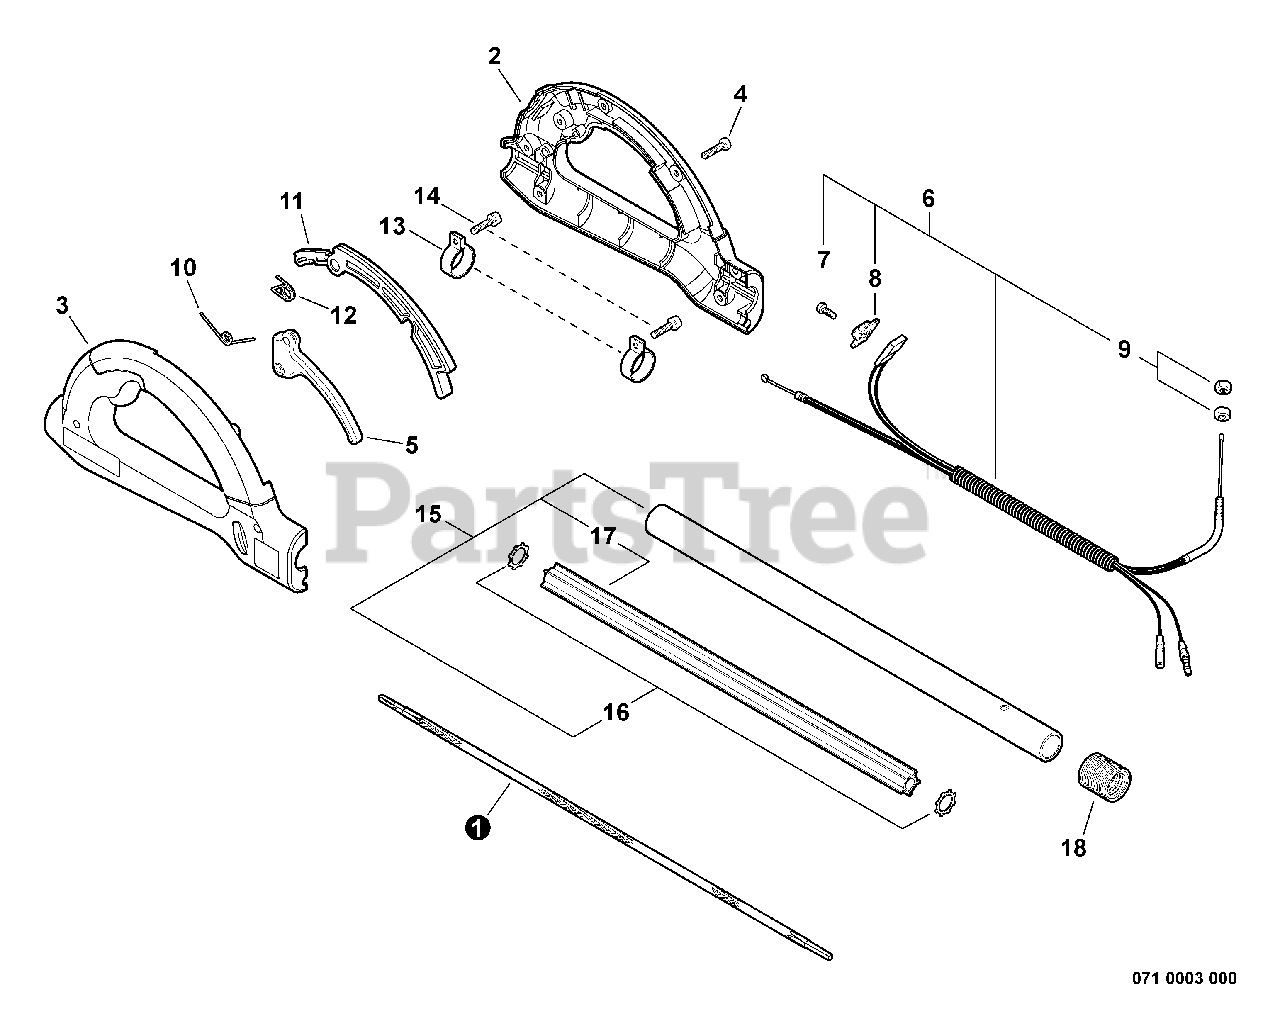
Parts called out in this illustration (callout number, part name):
1	DRIVESHAFT - FLEXIBLE
2	HANDLE - RIGHT
3	HANDLE - LEFT
4	SCREW - 5X18
5	TRIGGER, THROTTLE
6	CONTROL CABLE ASSY
7	SCREW - 3X10
8	KNOB, SWITCH - ORANGE
10	SPRING, TRIGGER
11	LEVER, TRIGGER LOCKOUT
12	SPRING, LOCKOUT LEVER
14	SCREW - 5X20
15	PIPE ASSY
18	TUBE, PROTECTIVE - CORRUGATED
